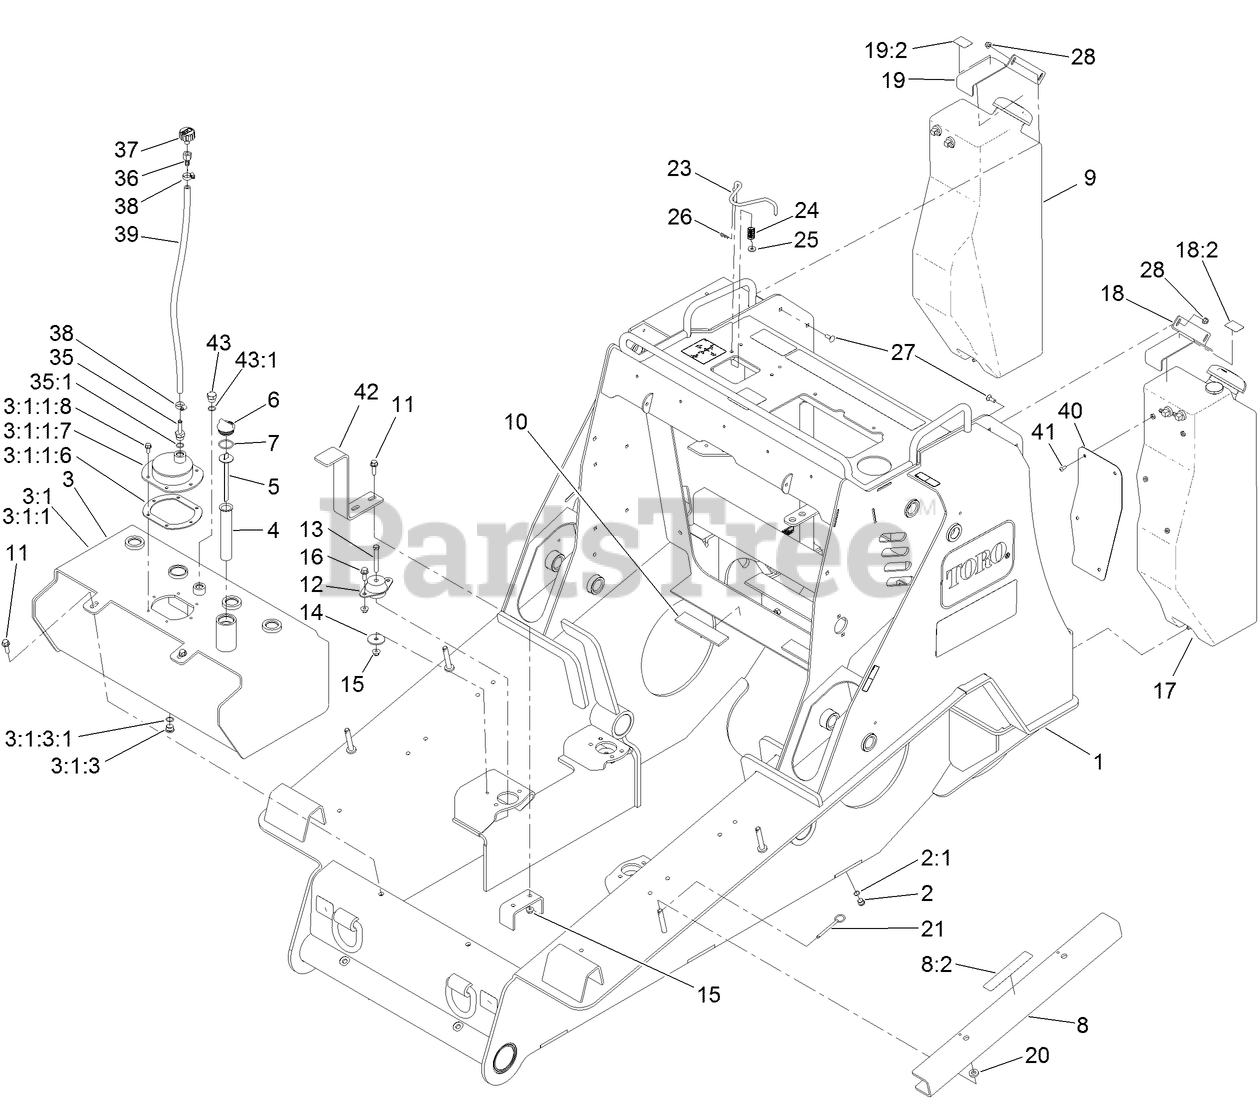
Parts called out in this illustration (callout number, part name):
1	FRAME ASM
2	PLUG-HEX, HOLLOW
2:1	O-RING
3	HYD TANK ASM
3:1	TANK-HYD
3:1:1	TANK-HYD, TOP
3:1:1:6	GASKET-COVER, ACCESS
3:1:1:7	COVER-ACCESS
3:1:1:8	SCREW-HHF
3:1:3	PLUG-HEX
3:1:3:1	O-RING
4	FILTER-SCREEN
5	DIPSTICK
6	PLUG-PLASTIC
7	O-RING
8	ARM-LOCKING
8:2	DECAL-DANGER
9	RH FUEL TANK ASM
10	PAD-RUBBER
11	SCREW-HHF
12	MOUNT-ENGINE
13	SCREW-HH
14	WASHER-REBOUND
15	NUT-HF, NI
16	SCREW-HHF
17	LH FUEL TANK ASM
18	BRACKET-TANK, LH
18:2	DECAL-ULTRA LOW SULFUR DIESEL
19	BRACKET-TANK, RH
19:2	DECAL-ULTRA LOW SULFUR DIESEL
20	WASHER-NEOPRENE
21	PIN-RING
23	ROD-INTERLOCK
24	SPRING-CONTROL
25	WASHER-FLAT
27	SCREW-CARR
28	NUT-HF, NI
35	FITTING-STR
35:1	O-RING
36	FITTING-FEMALE, BARBED
37	BREATHER
38	CLAMP-HOSE
39	HOSE-FUEL
40	PLATE-GUARD, TANK
41	SCREW-HSBH
42	STRAP-HOLD DOWN
43	PLUG-HYD, HH
43:1	O-RING
